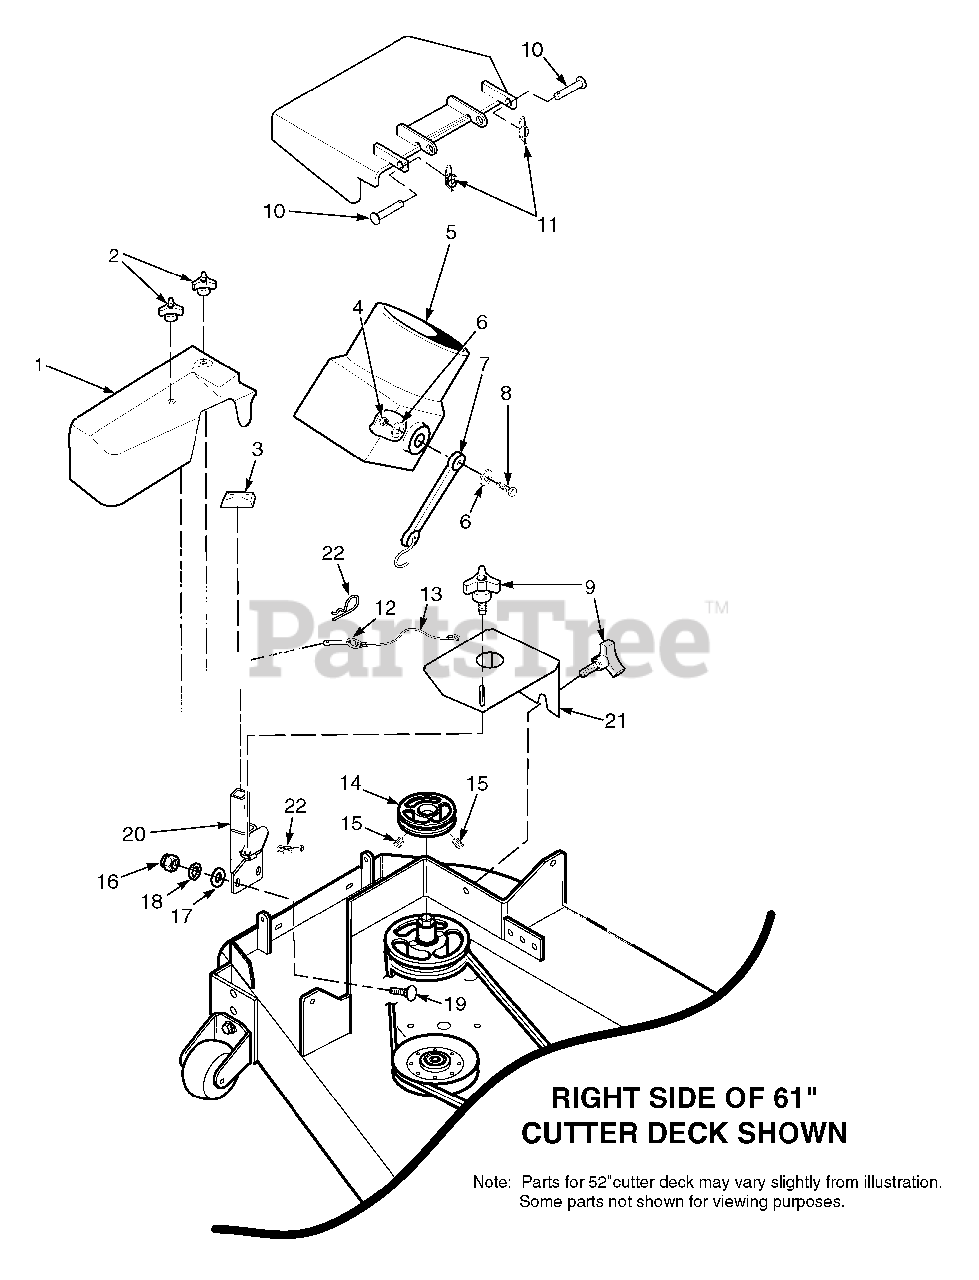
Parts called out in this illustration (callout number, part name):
1	Belt Cover, GC-STWC - 61"
2	Wingnut, Plastic 3/8 Small
3	Cap, Square Vinyl
4	Nut, Elastic Stop 1/4-20
5	Adapter, Blower GC-STT
6	Flatwasher, 1/4-.312 x .750 x .065
7	Rubber Strap 7-3/4"
8	Bolt, Hex Head 1/4-20 x 1-1/4"
9	Knob W/Stud, 3/8-16 x 1-1/4"
10	Clevis Pin, 5/16 x 1-1/2"
11	Pin, Rue Cotter 5/16 Dia.
12	Pin, Ring 1/2 x 2-1/4"
13	Lanyard
14	Pulley, 5-1/2" for 61" Deck
15	Setscrew, 5/16-18 x 3/8"
16	Nut, Elastic Stop 1/2-13
17	Lockwasher, 1/2"
18	Flatwasher, 1/2-.531 x 1.062 x .095
19	Bolt, Hex Head 1/2-13 x 1-1/2" Grade 5
20	Mounting Post Weldment, Blower - 61"
21	Belt Cover, GC-STWC-61
22	Hair Pin Cotter, .177 x 3-1/4"
